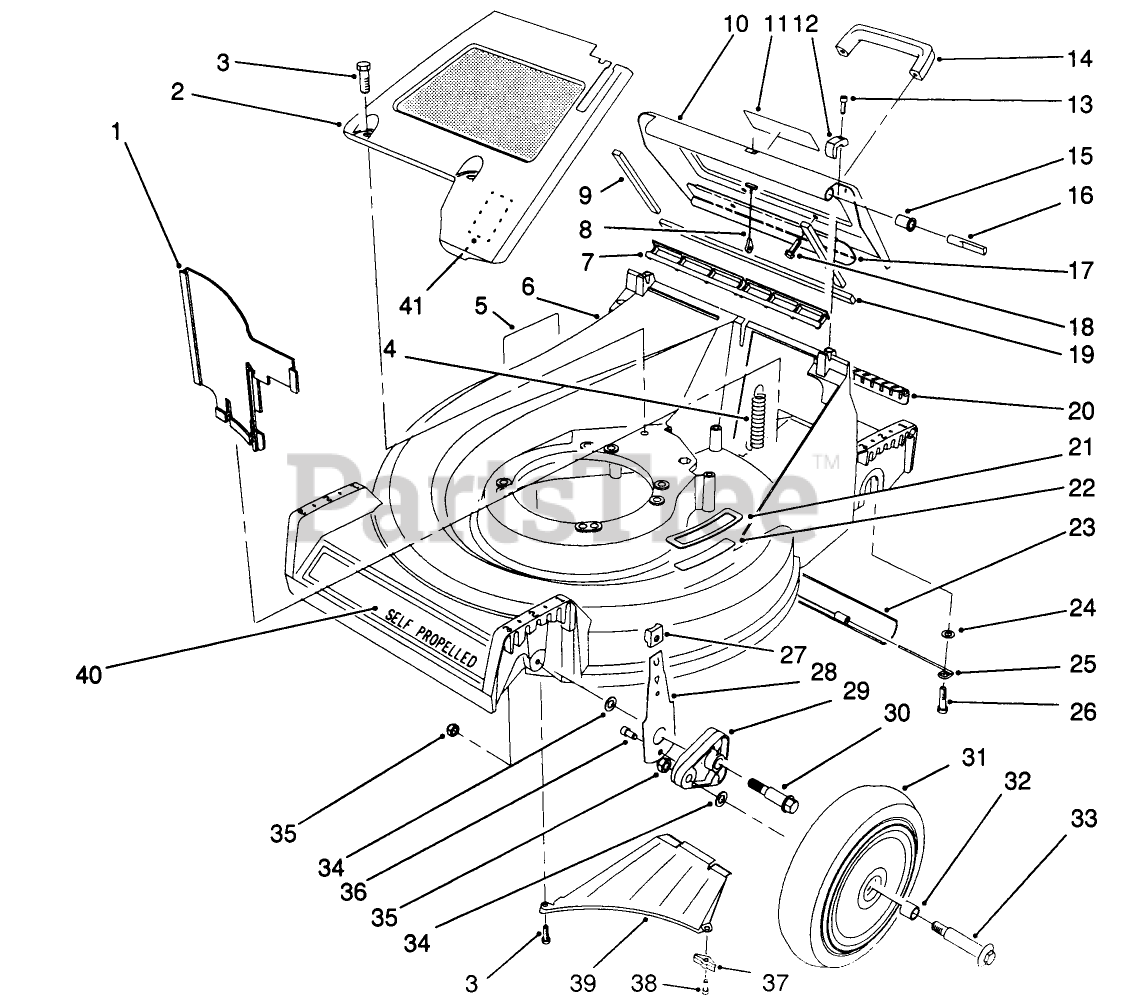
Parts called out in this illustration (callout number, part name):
1	PANEL-VERTICAL
3	SCREW-HWHTF
4	SPRING-EXTENSION
5	DECAL-DANGER
8	DOOR CABLE
13	SCREW-HSH
14	HANDLE-DOOR
15	DOOR BUSHING
18	SCREW-HWH
19	DOOR END SEAL
20	ACCESS COVER
21	STEP PAD
22	STEP PAD DECAL
23	TRAILING SHIELD
24	WASHER-PLAIN
25	SHIELD HANGER
26	SCREW-SHOULDER
27	KNOB-ARM
28	FRONT SPRING ARM ASM
29	ARM-PIVOT, FRONT
30	BOLT-SHOULDER
32	BUSHING
33	WHEEL BOLT
34	WASHER
35	NUT-LOCK
36	SCREW-HSH, THREAD FORMING
38	SCREW-HWHTF
41	DECAL - BBC ADJUST
